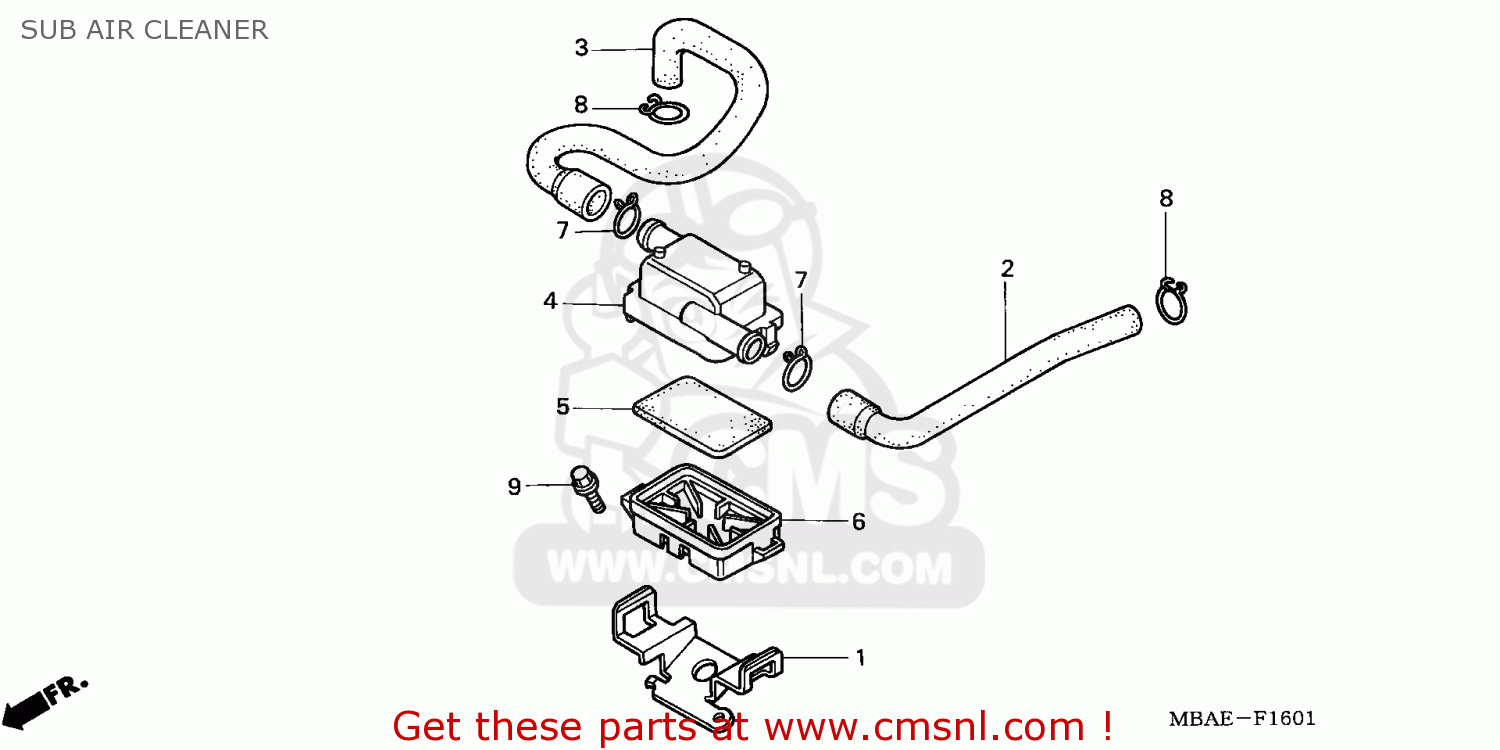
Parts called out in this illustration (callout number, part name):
1	STAY,SUB AIR/C
2	TUBE,SUB AIR/C FR
3	TUBE,SUB AIR/C RR
4	CASE,SUB AIR/C
5	FILTER,SUB AIR/C
6	COVER,SUB AIR/C
7	CLIP,TUBE
8	CLIP B16,TUBE
